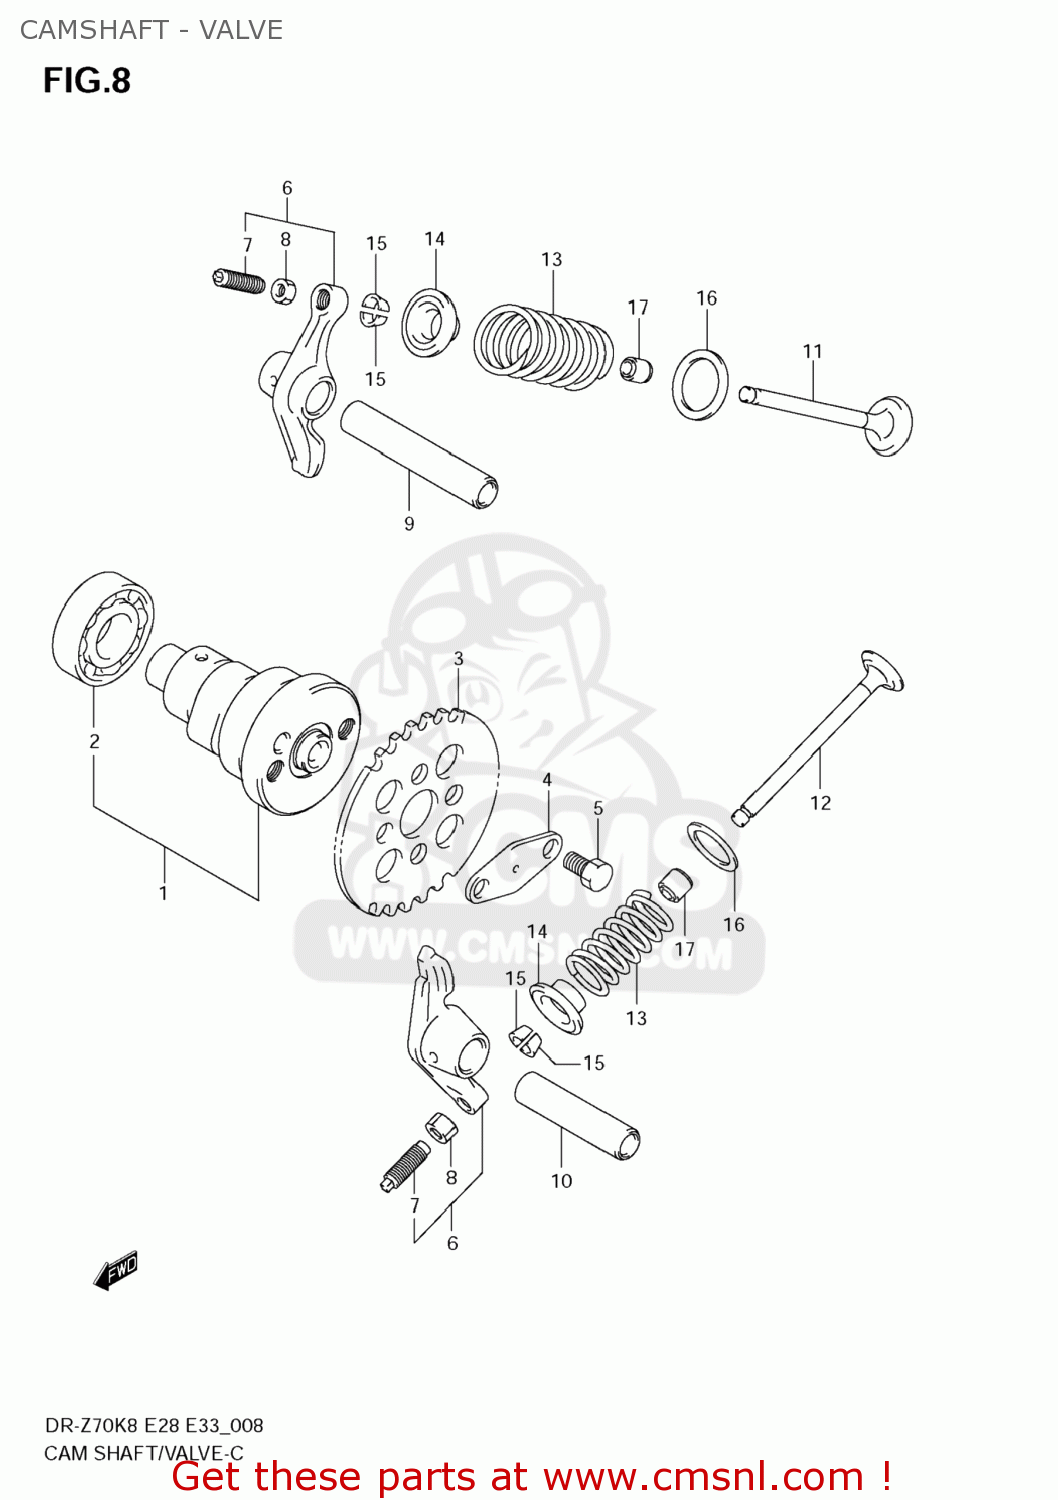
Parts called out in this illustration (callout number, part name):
1	CAMSHAFT ASSY
2	BEARING(15X32X9)
3	SPROCKET,CAMSHAFT
4	WASHER,SPROCKET
5	BOLT(6X10.5)
6	ARM,VALVE ROCKER
7	SCREW,TAPPET ADJUSTING
8	NUT,TAPPET ADJUSTING
9	SHAFT,VALVE ROCKER ARM INTAKE
10	SHAFT,VALVE ROCKER ARM EXHAUST
11	VALVE,INTAKE
12	VALVE,EXHAUST
13	SPRING SET,VALVE
14	RETAINER,VALVE SPRING
15	COTTER VALVE
16	SEAT,VALVE SPRING OUTER
17	SEAL,OIL(5X10.5X8.4)
